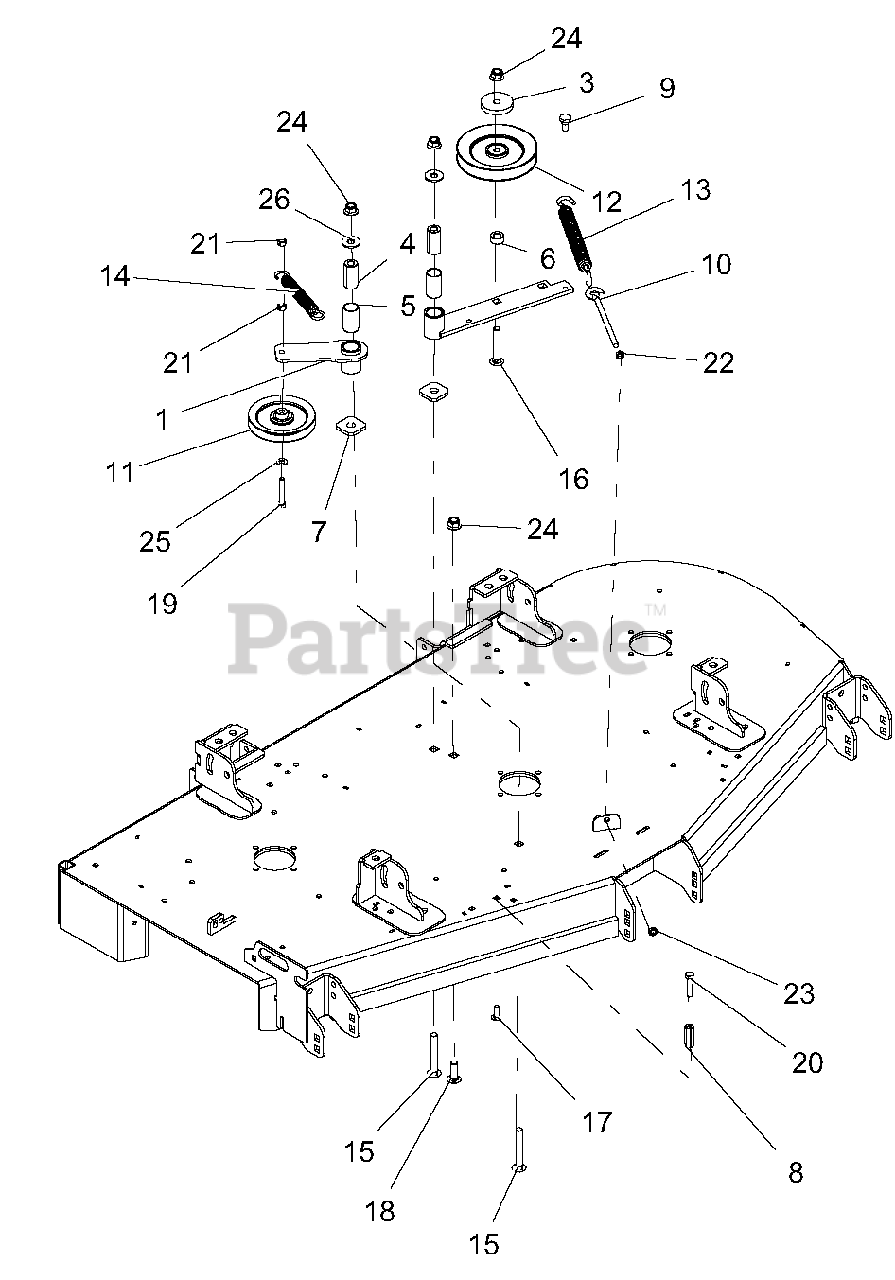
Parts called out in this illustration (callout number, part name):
1	WMT, IDLER PIVOT ARM-BLACK
3	CAP, IDLER BEARING SEALING
4	BSHG, SPCR .502X.997X2.03
5	BSHG, 1.00X1.125X1.937
6	BSHG, SPCR .502 X .997.50 PM
7	WSHR, -FLT.640X1.75X.250
8	NUT-HEX COUPLING
9	BLT, SHLDR EP .38-16X.30 HEX YZ
10	BOLT, .38-16X6.00 .62 DIA EYE
11	IDLER, V-5.00" W/.69 STANDOFF
12	SHEAVE, .50" ID X 6.00" OD V-IDLER
13	SPRG, EXTENSION
14	SPRG, EXTENSION
15	@BLT-RDHDSQNK .50-13X3.50 G5 Y
16	@BLT-RDHDSQNK .50-13X3.00 G5 Y
17	@BLT-RDHDSHSQNK.38-16X1.0 G5YZ
18	BLT-RDHDSQSHNK .50-13X1.50 YWZC
19	BLT-HEX .38-16X2.25 GR5 YWZC
20	BLT-HEX .38-16X1.75 GR5 YWZC
21	@NUT-LK-CTR .38-16 YWZC
22	NUT, JAM .375-16 YWZC
23	@NUT-LK-CTR-JAM .375-16 YWZC
24	NUT-LK-NYL-FLG .50-13 YWZC
25	@WSHR-FL-STL.406X.812X.065 YWZ
26	@WSHR-FL-STL.563X1.38X.109YWZC
